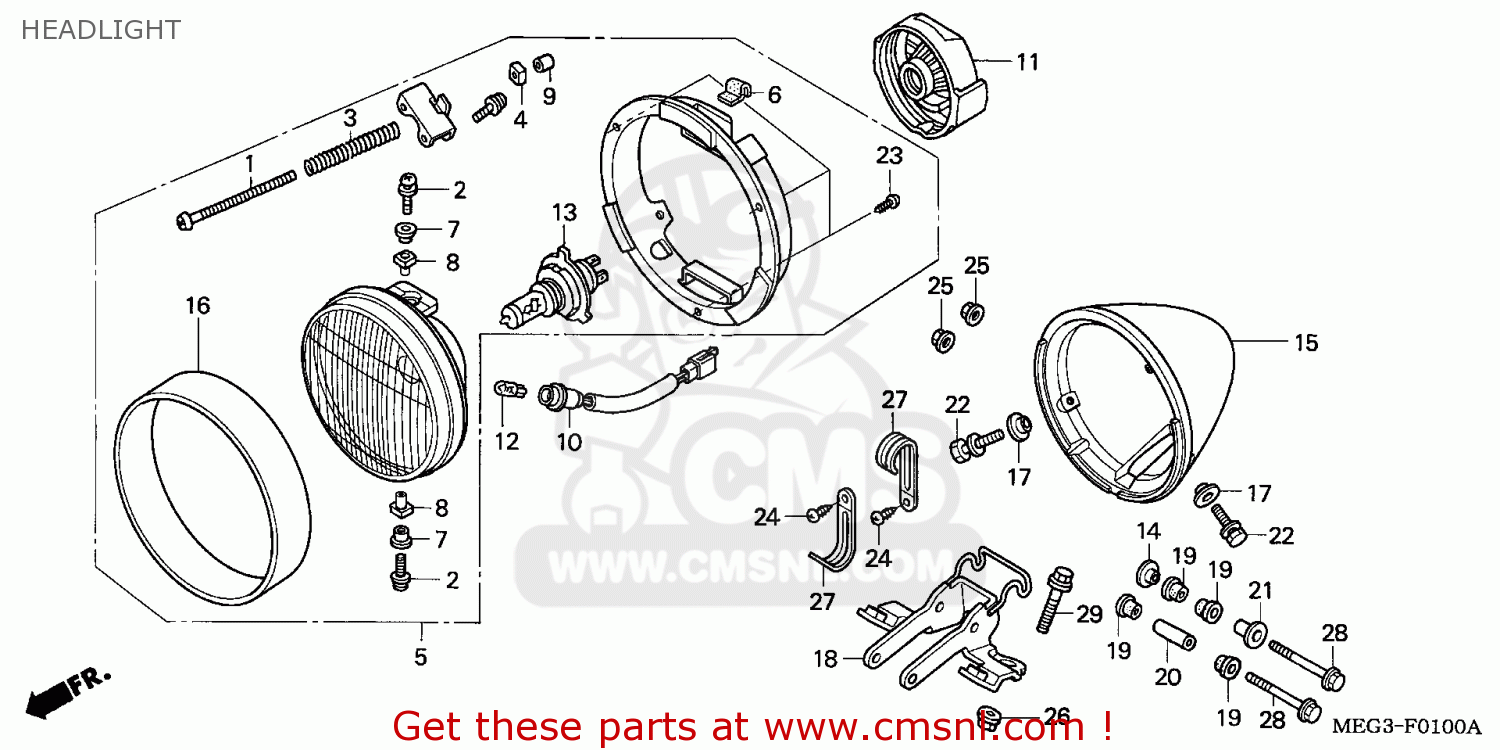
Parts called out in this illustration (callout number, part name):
1	SCREW,BEAM ADJUST
2	SCREW-WASH
3	SPRING,BEAM ADJUS
4	NOT,BEAM ADJ.
5	UNIT,HEAD LIGHT
6	WEAR RESISTANCETA
7	SPACER
8	NUT,UNIT HOLDER 1
9	COVER,SCREW
11	COVER,RUBBER
13	BULB,HEAD LIGHT (
14	COLLAR,CHAIN
15	CASE HEAD LIGHT
16	RIM HEAD LIGHT
17	WASHER,HEAD LIGHT
18	STAY,HEAD LIGHT
19	RUBBER,HEADLIGHT
20	COLLAR,HDLT.STAY
21	COLLAR,A
22	BOLT-WASH.,5X20
23	SCREW,TAPPING,4X12
24	SCREW,TAPPING4X12
25	NUT,FLANGE,6MM
27	CLIP,4X90
28	BOLT,FLANGE 6X55
29	BOLT,FLANGE,8X45
